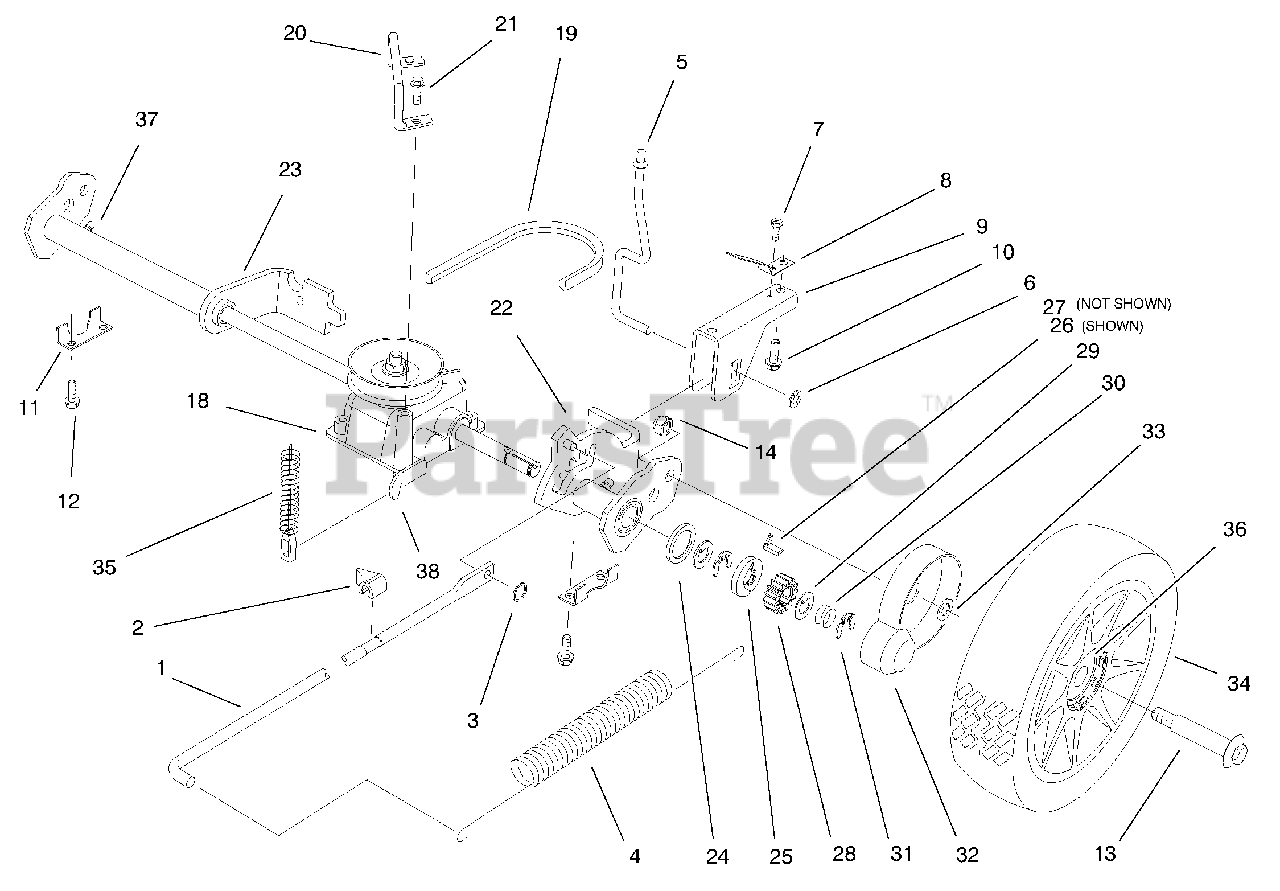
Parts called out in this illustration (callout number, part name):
1	Rod-Link
2	Indicator-HOC
3	Ring-Grip
4	Spring-Counterbalance
5	Rod-Trigger
8	Spring-Trigger Retainer
9	Saddle-HOC
11	Plate-Securing
12	Screw-HH Tap
13	Bolt-Shoulder
14	Nut-Lock
18	Gear Case Assembly
20	Retainer-Belt
21	Screw-HH Tap
22	Pivot Arm Assembly LH (Incl. Ref. #39-41)
23	Pivot Arm Assembly RH (Incl. Ref. #39-41)
24	Ring-Friction
26	Key-Rocking LH
27	Key-Rocking RH
28	Gear-Pinion
29	Washer-Thrust
30	Spring-Compression
31	Ring-Retaining
32	Cover-Wheel
33	Spacer-Wheel
34	Wheel & Tire Assembly (Incl. Ref. #36)
35	Spring-Compression
37	Fitting-Grease
38	Bracket-Traction
